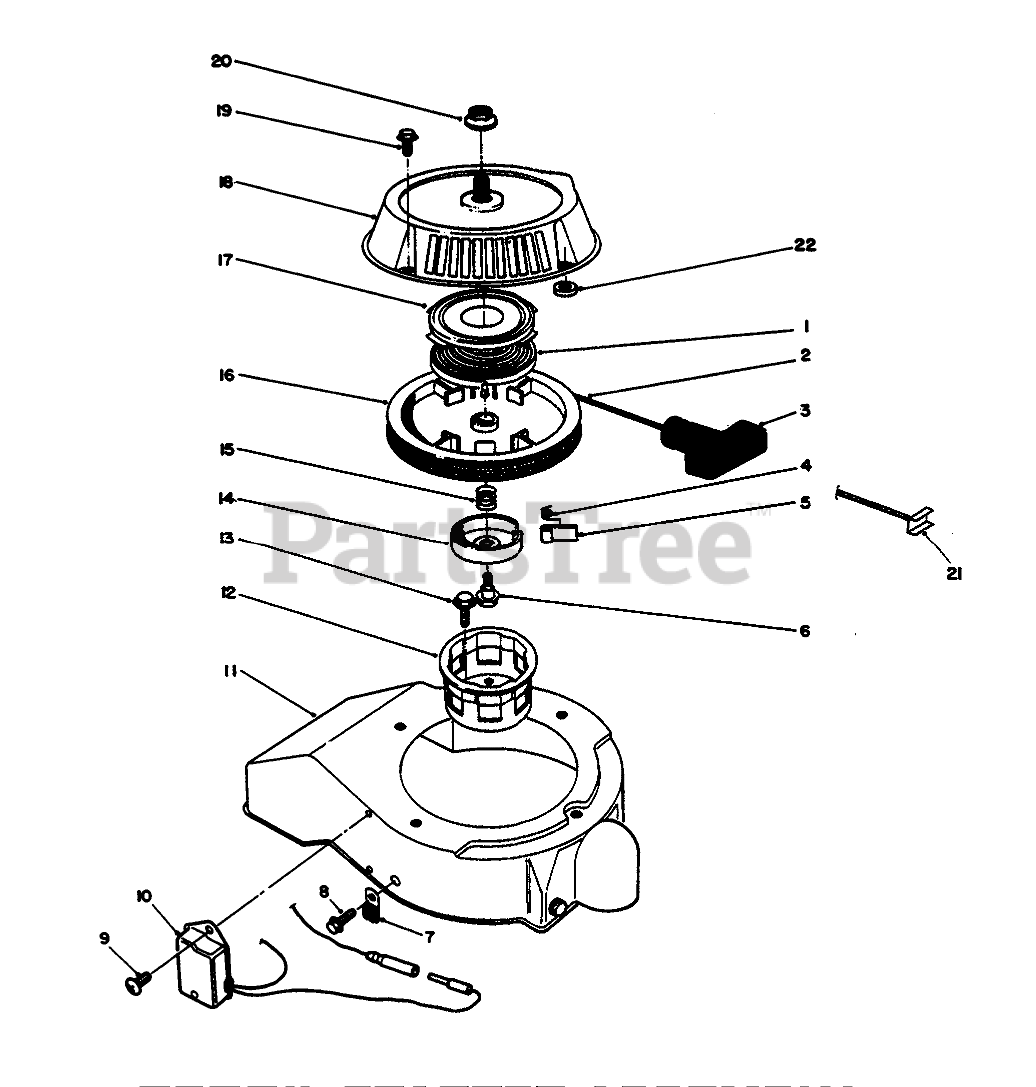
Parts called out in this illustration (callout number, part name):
1	Spring-Recoil
2	ROPE-STARTER
3	HANDLE-RECOIL
4	SPRING
7	CLAMP
9	SCREW
10	MODULE
11	SHROUD
12	CUP - STARTER
14	RETAINER
15	SPRING
17	Retainer-Recoil Spring
18	RECOIL CASE
19	MOUNTING SCREW
20	NUT (F/W & PPP)
21	Insert Handle
22	SPACER-PLATE, PIVOT
